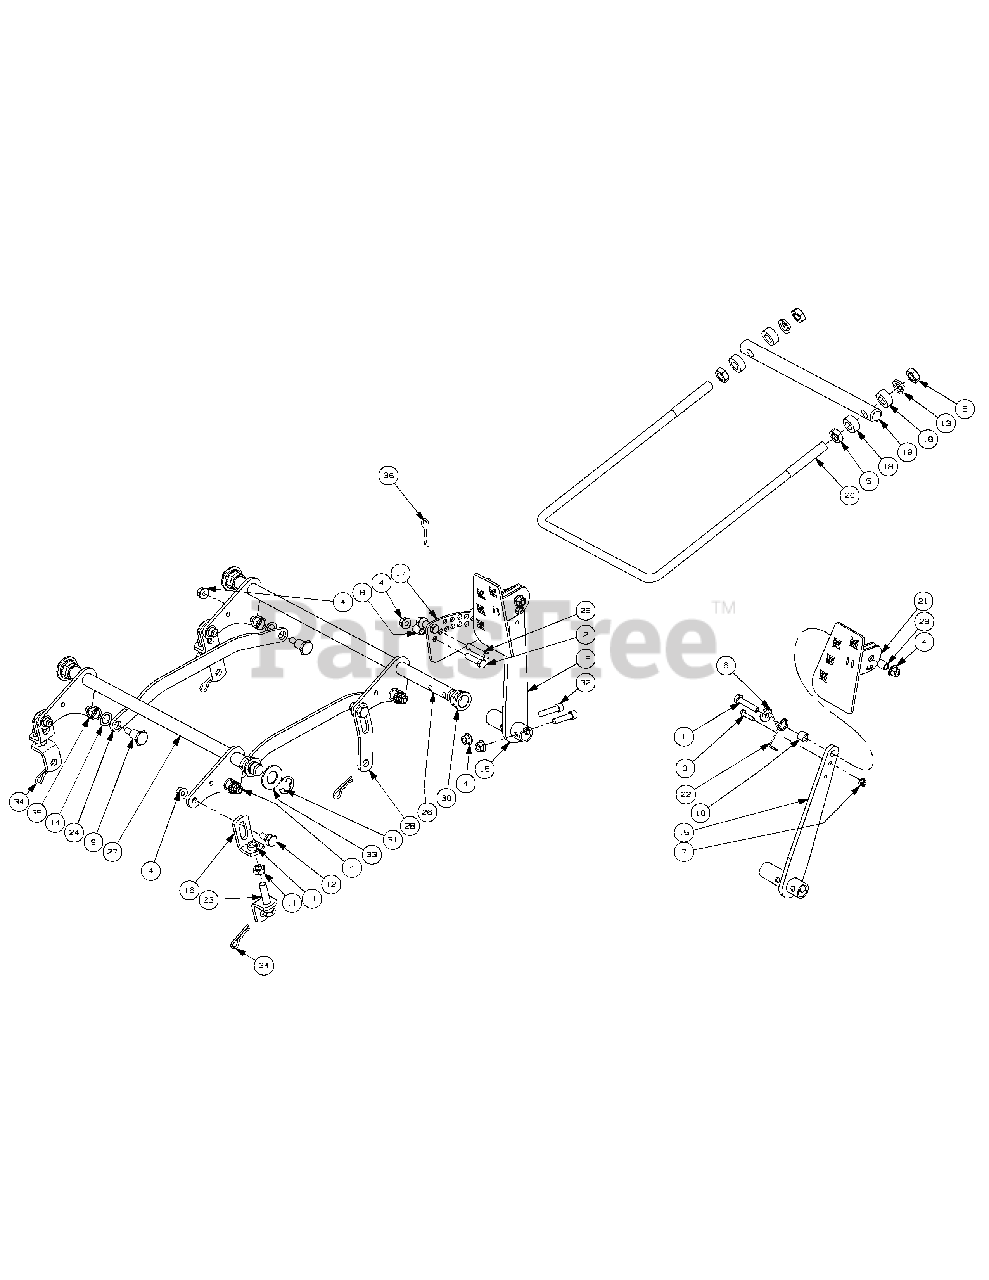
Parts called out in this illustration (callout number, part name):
1	Capscrew, 3/8-16 x 1-3/4
2	Hex Cap Screw, 3/8-16 x 1-1/2
3	Hex Cap Screw, 1/4-20 x 1.00
4	Nut, 3/8-16, Hex Flange Lock
5	Jam Nut, 5/8-11
6	Idler Washer
7	Nut, 1/4-20, Hex Flange Lock Nut
8	Spacer, .375 x .50 x .75 Lg
9	Shoulder Screw, 0.625 OD x .830 Lg.
10	Spacer, .625 OD x .385 ID x 1/2
11	Jam Nut, 1/2-20
12	Shoulder Screw, 3/8-16, .56 x .27
13	Lock Washer, 5/8
14	Washer, 1.00 OD x .625 ID x .048
15	Foot Lift Pivot Assembly
16	Deck Lift Bracket
17	Index Plate
18	Spacer, .635 ID x 1.188 OD x .406
19	Trail Link Pivot Rod
20	Front Lift Rod
21	Foot Pedal Assembly
22	Foot Lift Torsion Spring
23	Lower Lift Bracket Assembly
24	Lift Link
25	Clevis Pin, .375 x 1.89 x 2.125
26	Front Shaft Assembly
27	Rear Shaft Assembly
28	Link Plate
29	Spacer, .380 ID x .500 OD x .605
30	Hex Flange Bearing, .875 ID
31	E Clip, .875 Dia.
32	Sockethead Capscrew, 3/8-16 x 1.50
33	Flat Washer, .94 x 1.75 x .11
34	Hair Pin
35	Spacer, .628 ID x .875 OD x .500
36	Hair Pin
